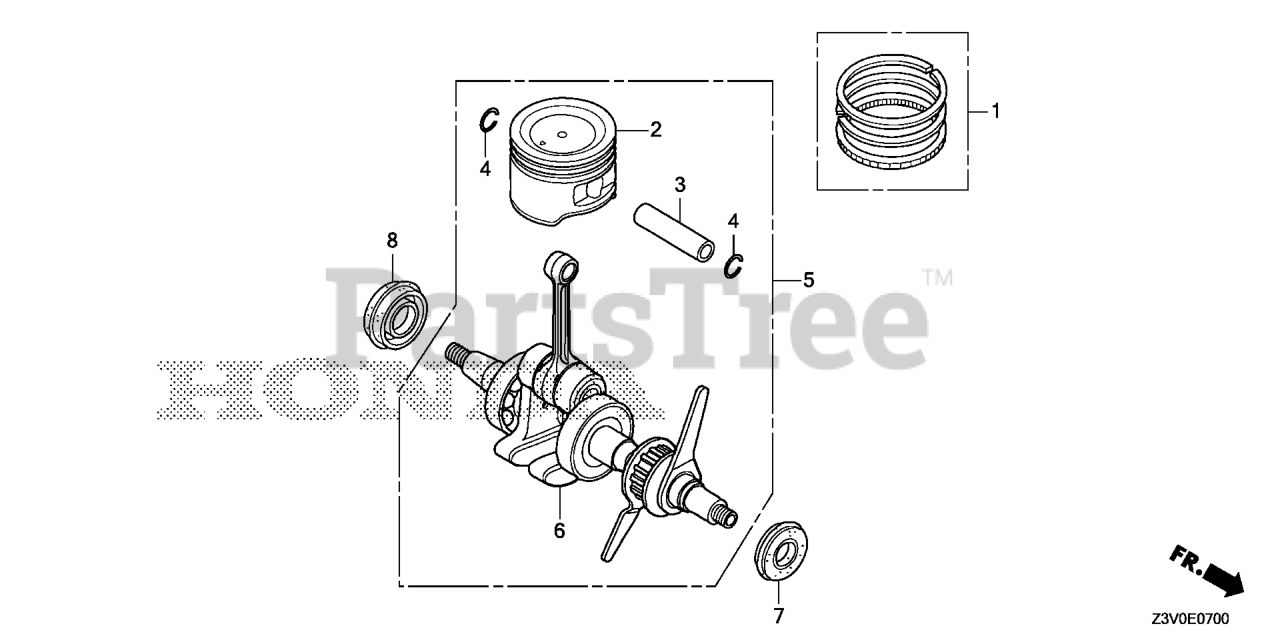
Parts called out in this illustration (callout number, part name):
1	RING SET, PISTON
3	PIN, PISTON
4	CLIP, PISTON PIN (9MM)
5	CRANKSHAFT
6	CRANKSHAFT
7	OIL SEAL (10X20X5)
8	OIL SEAL (15X25X6)
